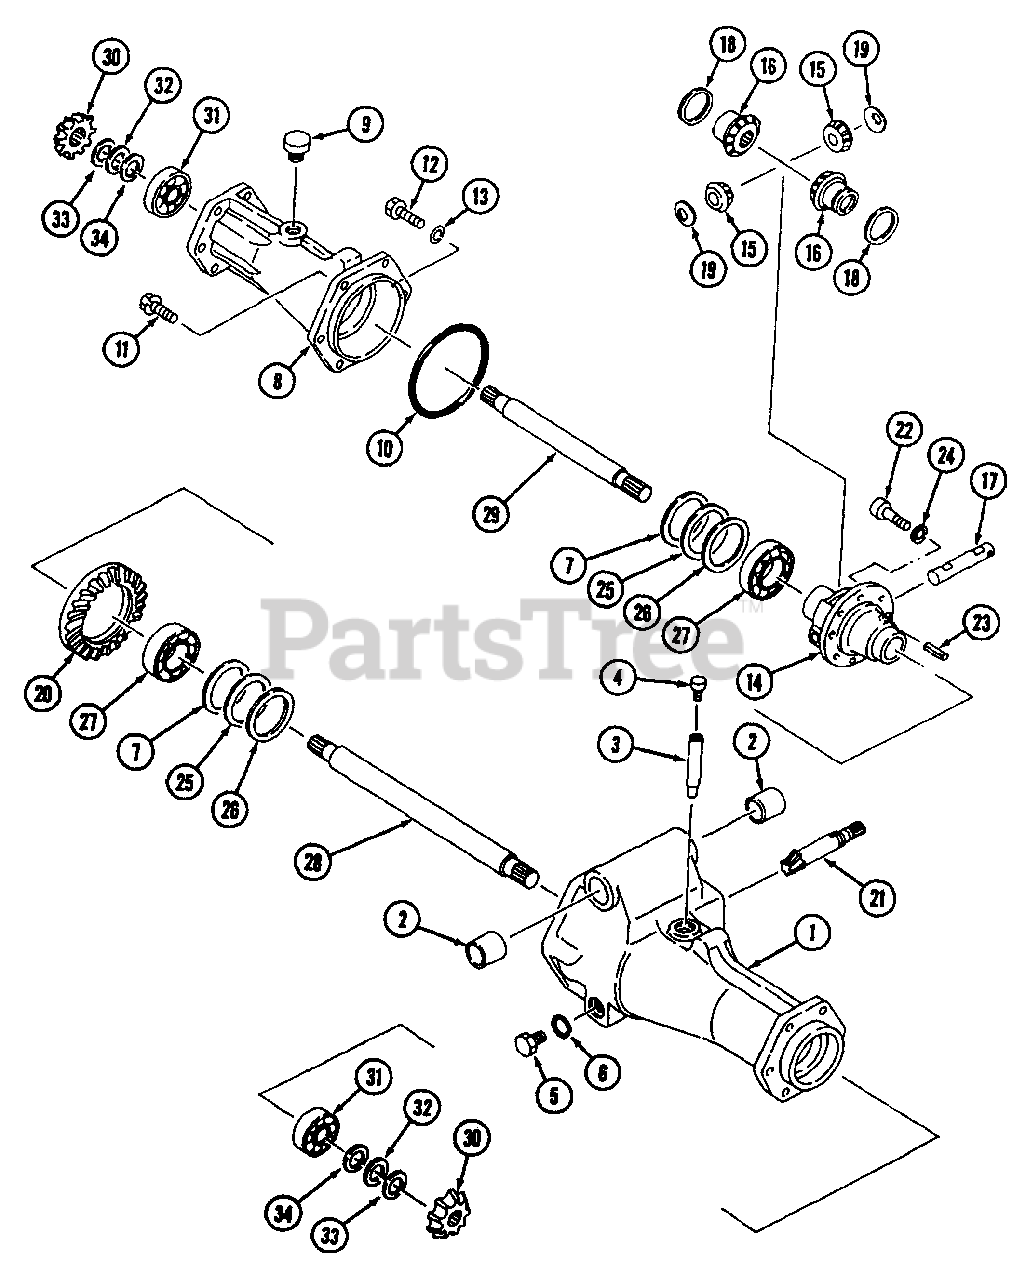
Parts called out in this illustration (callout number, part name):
1	Housing Axle A
8	Housing Axle B
18	Washer, Thrust
19	Washer, Thrust
20	Gear Ring
21	Shaft Pinion
28	Shaft Diff. L.H.
29	Shaft Diff. R.H.
